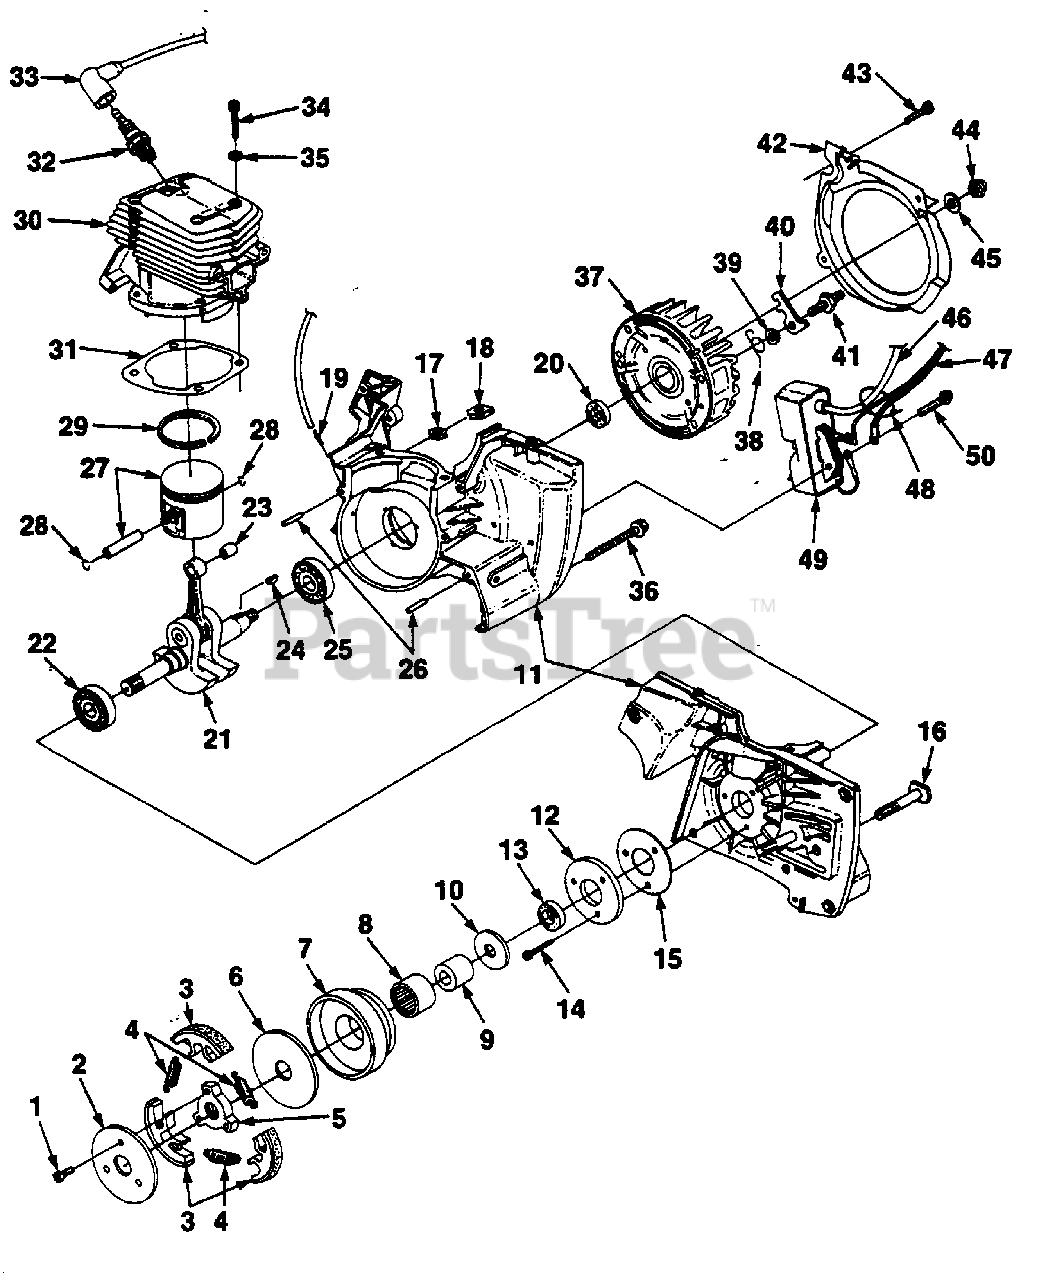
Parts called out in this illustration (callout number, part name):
1	SCREW- Pan Hd. (8-32 x 3/8")
2	COVER- Clutch
3	SHOE- Clutch
4	SPRING- Clutch
5	SPIDER- Clutch
6	WASHER- Thrust
7	PULLEY- Drum & Bearing
8	BEARING- Needle
9	RACE- Inner
10	WASHER- Thrust
11	CRANKCASE ASSEMBLY
12	RETAINER- Bearing
14	SCREW- Socket cap (10-24 x 5/8")
15	GASKET- Bearing & Retainer
16	BOLT- Guide bar
17	NUT- Lock hex (10-24)
18	RETAINER- Nut
19	FITTING- Tubing
20	SEAL
21	CRANKSHAFT
22	BEARING- Ball
23	BEARING- Roller
24	KEY- Woodruff
25	BEARING- Ball
26	PIN- Dowel
27	PISTON & PIN ASSEMBLY
28	RING- Retainer
29	PISTON RING
30	CYLINDER
31	GASKET- Cylinder
32	SPARK PLUG- (CJ6Y)
33	TERMINAL- Spark plug
34	SCREW- Cap socket hd. (10-24 x 1 1/8")
35	WASHER- Conical
36	SCREW- Hex sems (10-24 x 2")
38	SPRING- Starter pawl
39	WASHER- Retainer
40	PAWL- Starter
41	STUD- Shoulder
42	SCROLL- Air guide
43	SCREW- Mach. pan hd. (6-32 x 3/8")
44	NUT- Hex locking (3/8-24)
45	WASHER- Flat
46	LEAD- High tension
47	LEAD- Ground (See Fig. 1, #9)
48	CABLE- Tie
50	SCREW- Hex sems (#10-24 x 1")
